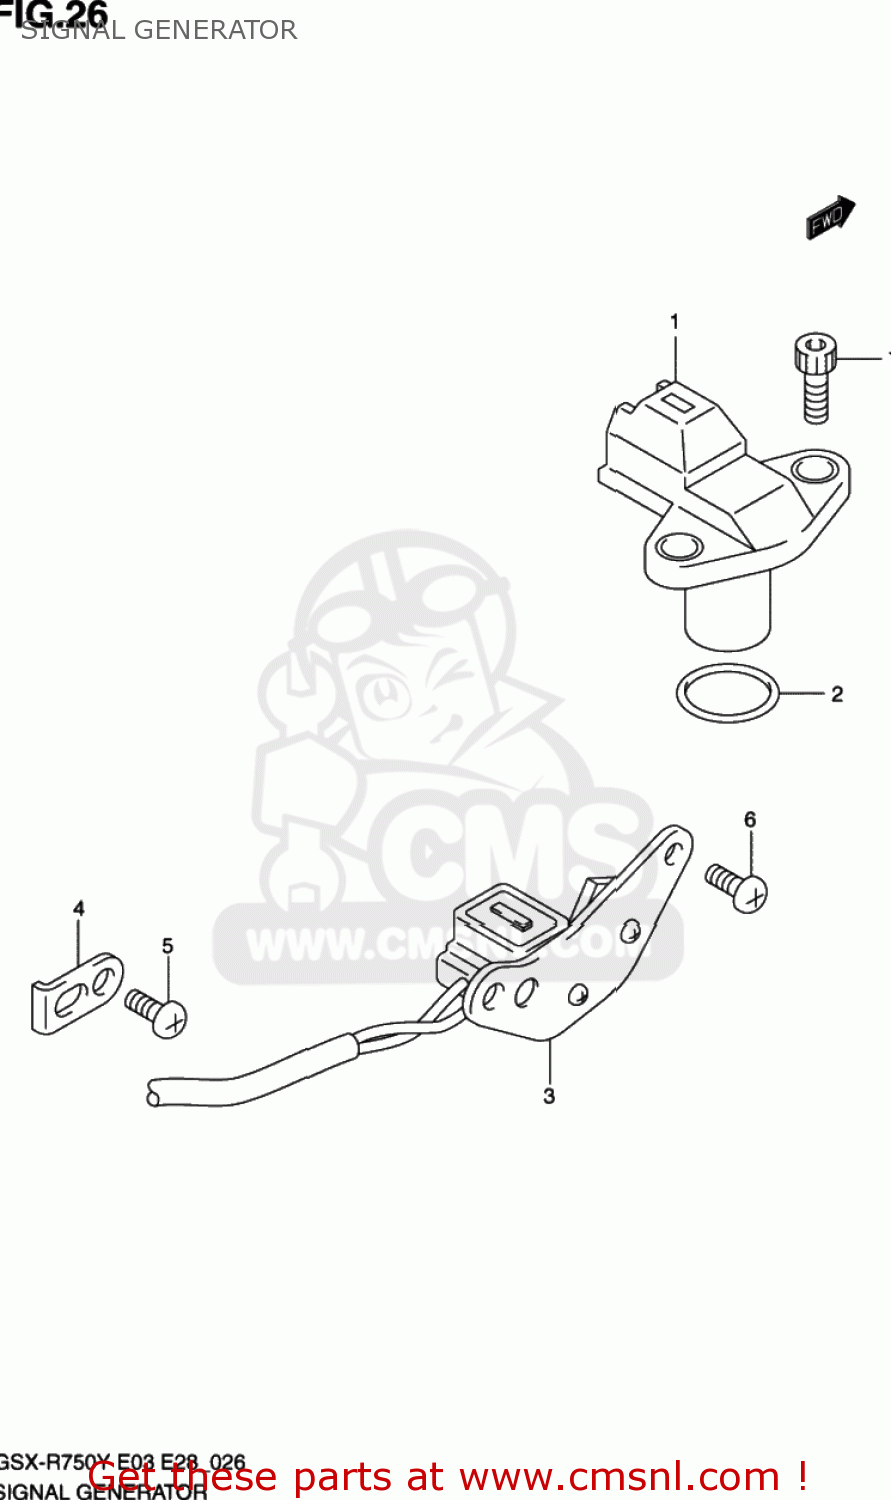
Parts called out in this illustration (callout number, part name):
1	SENSOR ASSY,CAM POSITION
2	PACKING (NAS)
3	STARTER SIGNAL GENERATOR
4	CLAMP,SIGNAL GENERATORERATOR
5	SCREW
6	SCREW
7	BOLT,OIL FILLE
